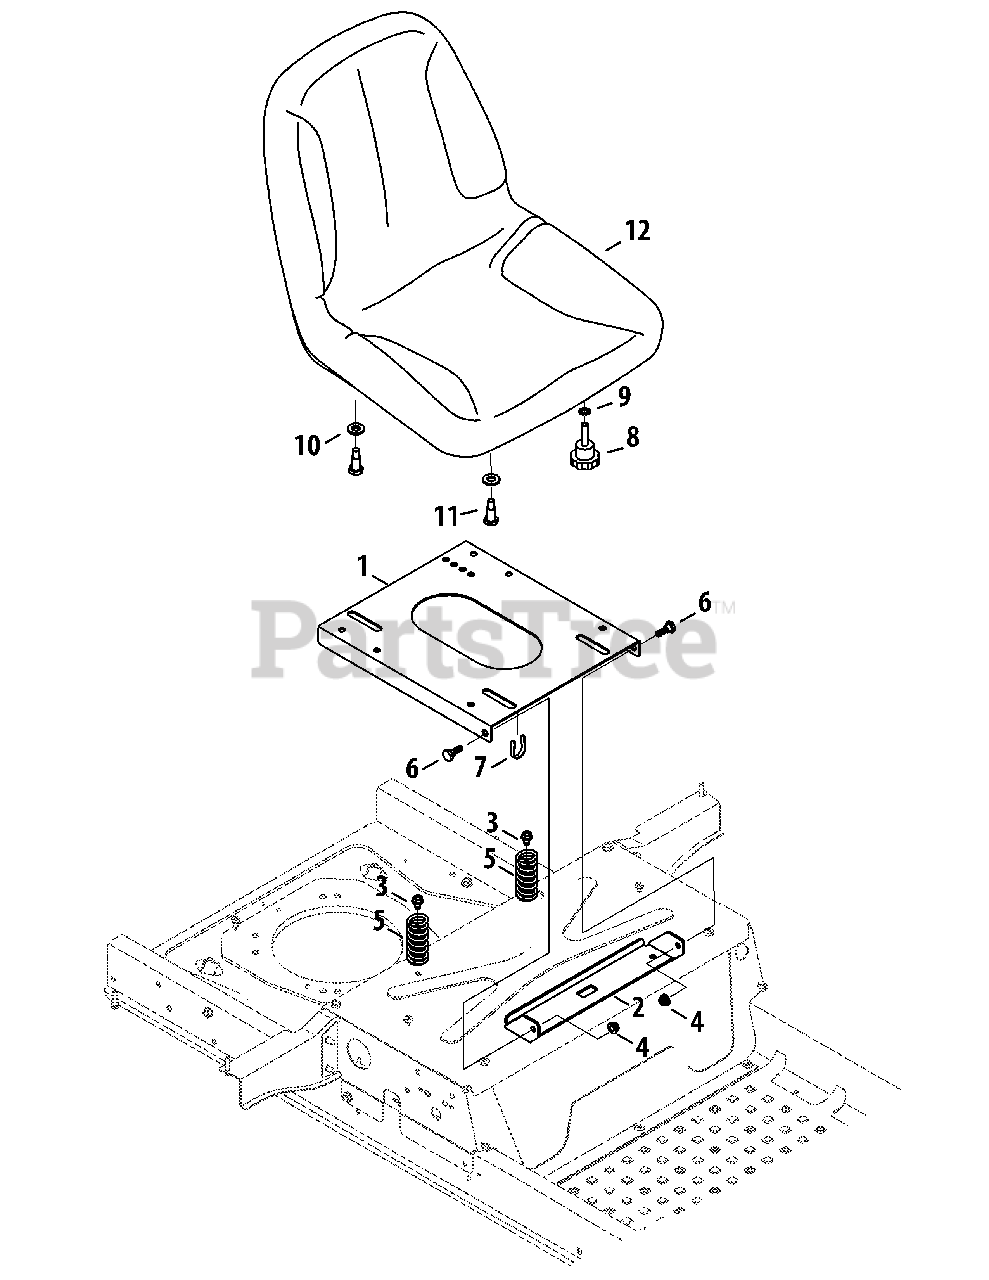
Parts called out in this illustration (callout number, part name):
1	Seat Mount Bracket
2	SEAT PIVOT BRACKET (POWDER BLACK)
3	Hex Washer Screw, 5/16-18 x .750
4	Flange Lock Nut, 5/16-18
5	Spring, Compression, 1.28 OD x 3.125 Lg
6	Shoulder Screw, .437 x .268, 5/16-18
8	Knob Assembly
9	External Tooth Lock Washer, 3/8
10	Flat Washer, .510 x 1.00 x .125
11	Shoulder Screw, 3/8-16
12	Seat
